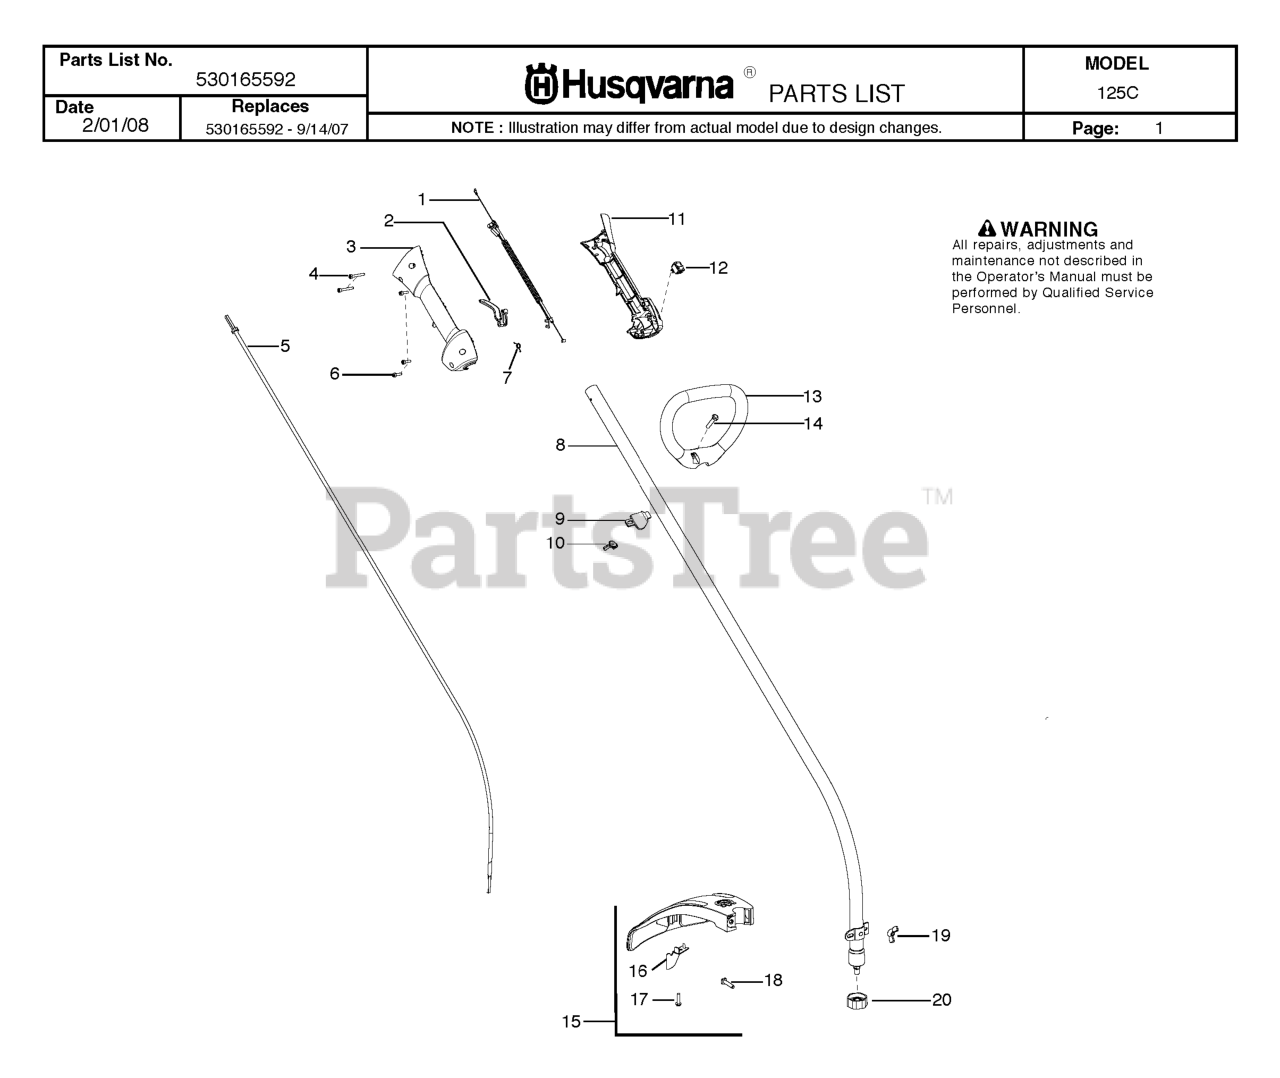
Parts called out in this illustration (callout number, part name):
1	KIT-AIR BOX W/CABLE WIRE HARN
1	ASSY-CABLE WIRE HARNESS
2	TRIGGER THROTTLE
3	HOUSING-THROTTLE (RH)
5	FLEX SHAFT 52"
6	SCREW M4 X 1.75 PT 16MM
7	SPRING TRIGGER
8	DRIVESHAFT KIT
9	CLAMP ASSIST HANDLE
10	WINGNUT, TYPE 2
11	HSG THROTTLE LH
12	KIT SWITCH
14	BOLT, TYPE 2
15	TRIMMER GUARD 128C
16	KIT - LIMITER - LINE
18	BOLT, TYPE 2
19	WINGNUT, TYPE 2
